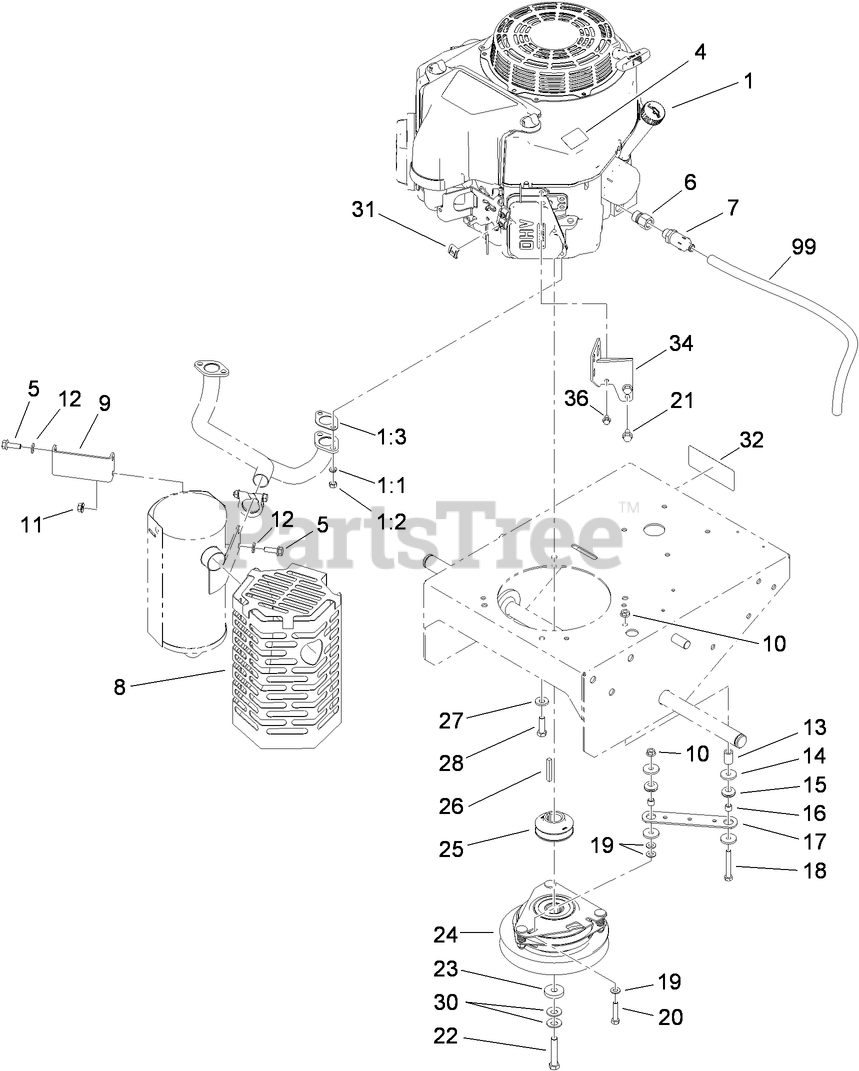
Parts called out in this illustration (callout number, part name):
1:1	WASHER-LOCK
1:3	GASKET-EXHAUST
4	DECAL-WARNING
5	SCREW-HHF
6	Adapter
7	VALVE-DRAIN, OIL
8	SHIELD-MUFFLER
9	BRACKET-SHIELD, MUFFLER
10	NUT-HF
11	NUT-HF, LOCK
12	WASHER-SPRING
13	TUBE-RETAINER
14	WASHER
15	GROMMET
16	SPACER
17	STRAP-CLUTCH, BRAKE
18	SCREW-HH
19	WASHER-PLAIN
20	SCREW-HH
21	SCREW-HHF
22	SCREW-HH
23	WASHER
24	CLUTCH / BRAKE ASM
25	PULLEY-DRIVE
26	KEY-SQUARE
27	WASHER-BELLEVILLE
28	SCREW-HH
30	WASHER-SPRING
31	CLAMP-CABLE
32	DECAL-CAUTION
34	BRACKET-MUFFLER
36	SCREW-HHF
99	HOSE-DRAIN, OIL
